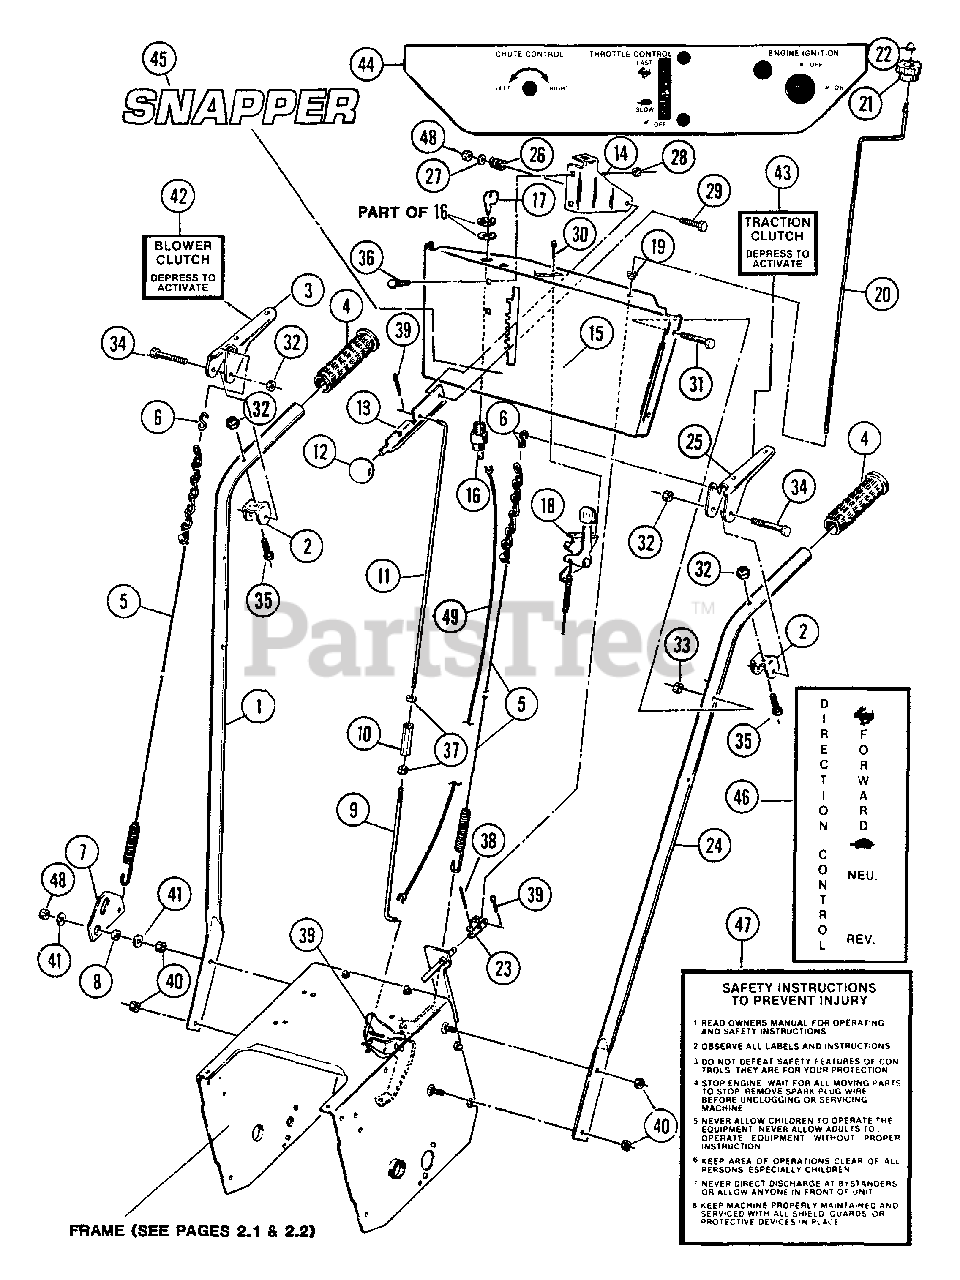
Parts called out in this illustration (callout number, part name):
1	ASSEMBLY, R.H. Handle Bar
2	BRACKET, Handle
3	HANDLE, Right
4	GRIP, Handle
5	CABLE, Clutch
6	S-HOOK
7	LEVER, Clutch
8	SPACER
9	ROD, Lower Shift
10	CONNECTOR
11	ROD, Upper Shift
12	KNOB, Shift Handle
13	HANDLE, Shift
14	BRACKET, Shift Lever
15	PANEL, Control
16	SWITCH, Ignition
17	KEY
18	CONTROL, Throttle (Briggs Engines)
18	CONTROL, Throttle (Tecumseh Engines)
19	BUSHING
20	CRANK, Chute
21	KNOB, Chute Crank
22	CAP, Push
23	CONNECTOR, Chute Crank
24	ASSEMBLY, L.H. Handle Bar
25	HANDLE, Left
26	SPRING, Shift Lever
27	WASHER, 5/16 SAE
28	NUT, 1/4-20 Hex Flange Lock
29	SCREW, 5/16-18 x 1" Hex Head Cap, Grade 2
30	SCREW, #10-24 x 1/2" Hex Washer Self-Tap (Torx)
31	SCREW, 5/16-24 x 1-1/2" Hex Head Cap, Grade 2
32	NUT, 1/4-28 Hex Top Lock
33	NUT, 5/16-24 Hex Center Lock
34	SCREW, 1/4-24 x Hex Head Cap, Grade 5
35	SCREW, 1/4-28 x 1-3/8" Hex Head Cap, Grade 5
36	BOLT, 1/4-20 x 1/2" Short Neck Carriage, Grade 5
37	NUT, 3/8-16 Hex
38	PIN, 1/8" x 1" Roll
39	PIN, 1/8 x 1" Cotter
40	NUT, 5/16-18 Hex Flange, Grade 5
41	WASHER, 5/16" x 1-1/4" x 3/32" Flat
42	DECAL, Blower Clutch
43	DECAL, Traction
45	DECAL, Snapper
46	DECAL, Directional Control
47	DECAL, Instruction
48	NUT, 5/16-18 Hex Center Lock
